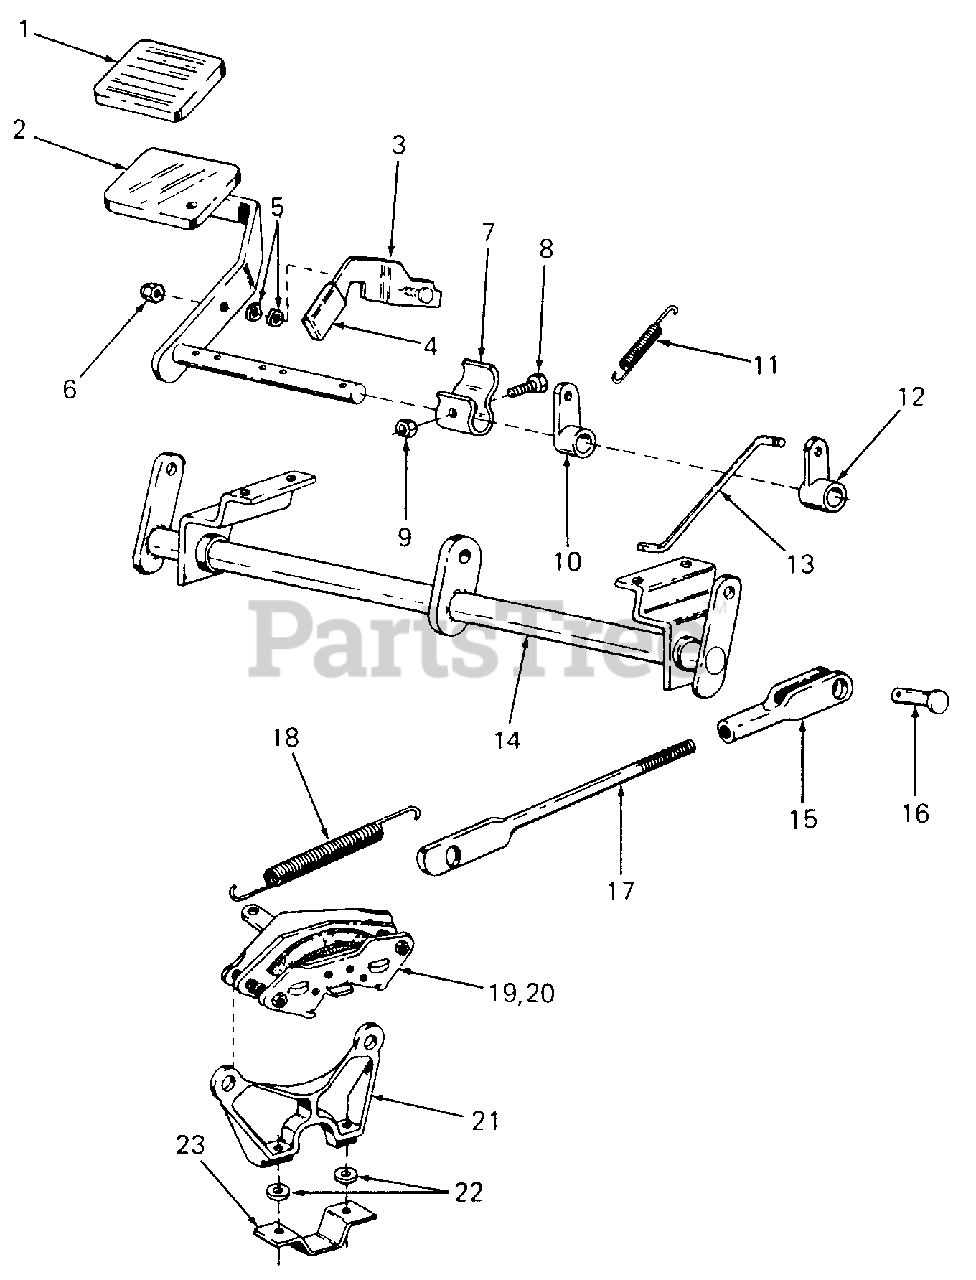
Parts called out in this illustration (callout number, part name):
1	Pad, Pedal
2	Pedal Assy, Brake
5	Washer, Wave, 1/4 Dia
6	Nut, Hex Insert Lock, 1/4-20
7	Spring, Switch Operating
8	Screw, Hex Cap, 1/4-20 X .75 Lg GR5
9	Nut, Hex Center Lock, 1/4-20
11	Spring, Return
13	Rod, Brake Lever
15	Clevis, Adj
16	Pin, Clevis, 3/8 Dia X 1.0 Lg
17	Rod, Brake
18	Spring, Extension
19	Brake Kit, LH - Caliper
20	Brake Kit, RH - Caliper
21	Bracket, Brake Mounting
22	Washer, Flat, .406 X .812 X .134 Thk
23	Bracket, Caliper Flange Mounting
